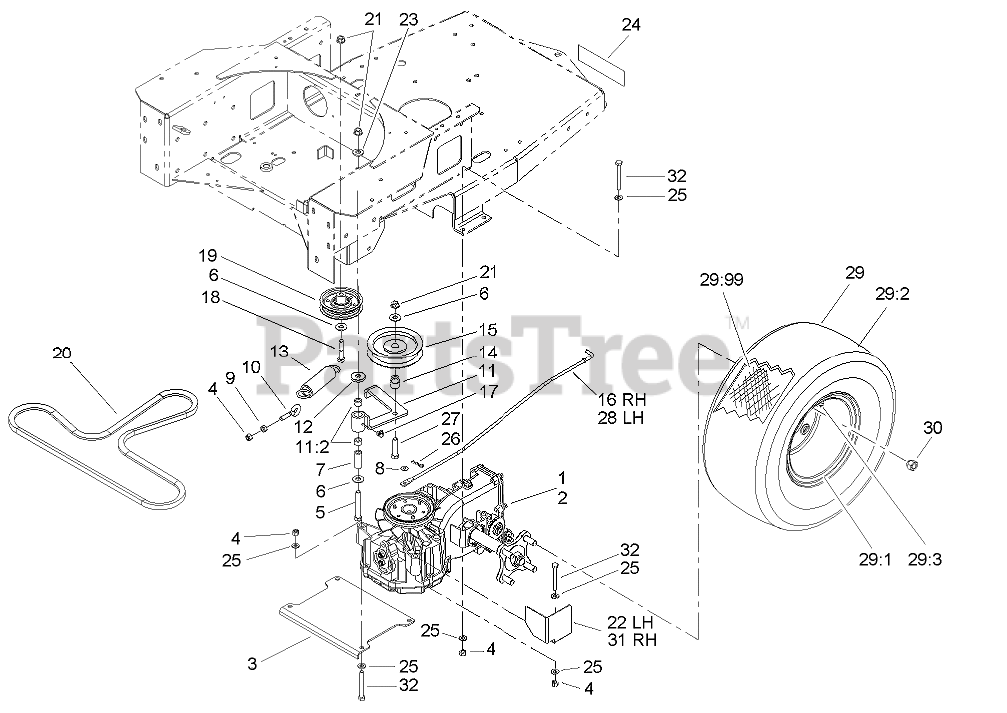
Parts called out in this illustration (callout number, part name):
1	Hydro-LH
2	Hydro-RH
3	PLATE-HYDRO, LOWER
4	NUT-LOCK, NI
5	SCREW-HH
6	WASHER-FLAT
7	BUSHING
8	WASHER-FLAT
9	NUT-HF
10	BOLT-EYE
11	IDLER ARM ASM
11:2	SLEEVE-BEARING
12	SPACER
13	SPRING-EXTENSION
14	BUSHING-IDLER
15	PULLEY-IDLER
16	ROD-RH
17	FITTING-GREASE, 90 DEG
18	SCREW-HH
19	PULLEY-IDLER
20	BELT-V
21	NUT-HF
22	GUARD-FAN, LH
23	WASHER-BELLEVILLE
24	DECAL-TRANSPORT
25	WASHER-PLAIN
26	PIN-COTTER
27	SCREW-HH
28	ROD-LH
29	WHEEL AND TIRE ASM
29:3	STEM-VALVE
29:99	TUBE-TIRE
30	NUT-LUG
31	GUARD-FAN, RH
32	SCREW-HH
